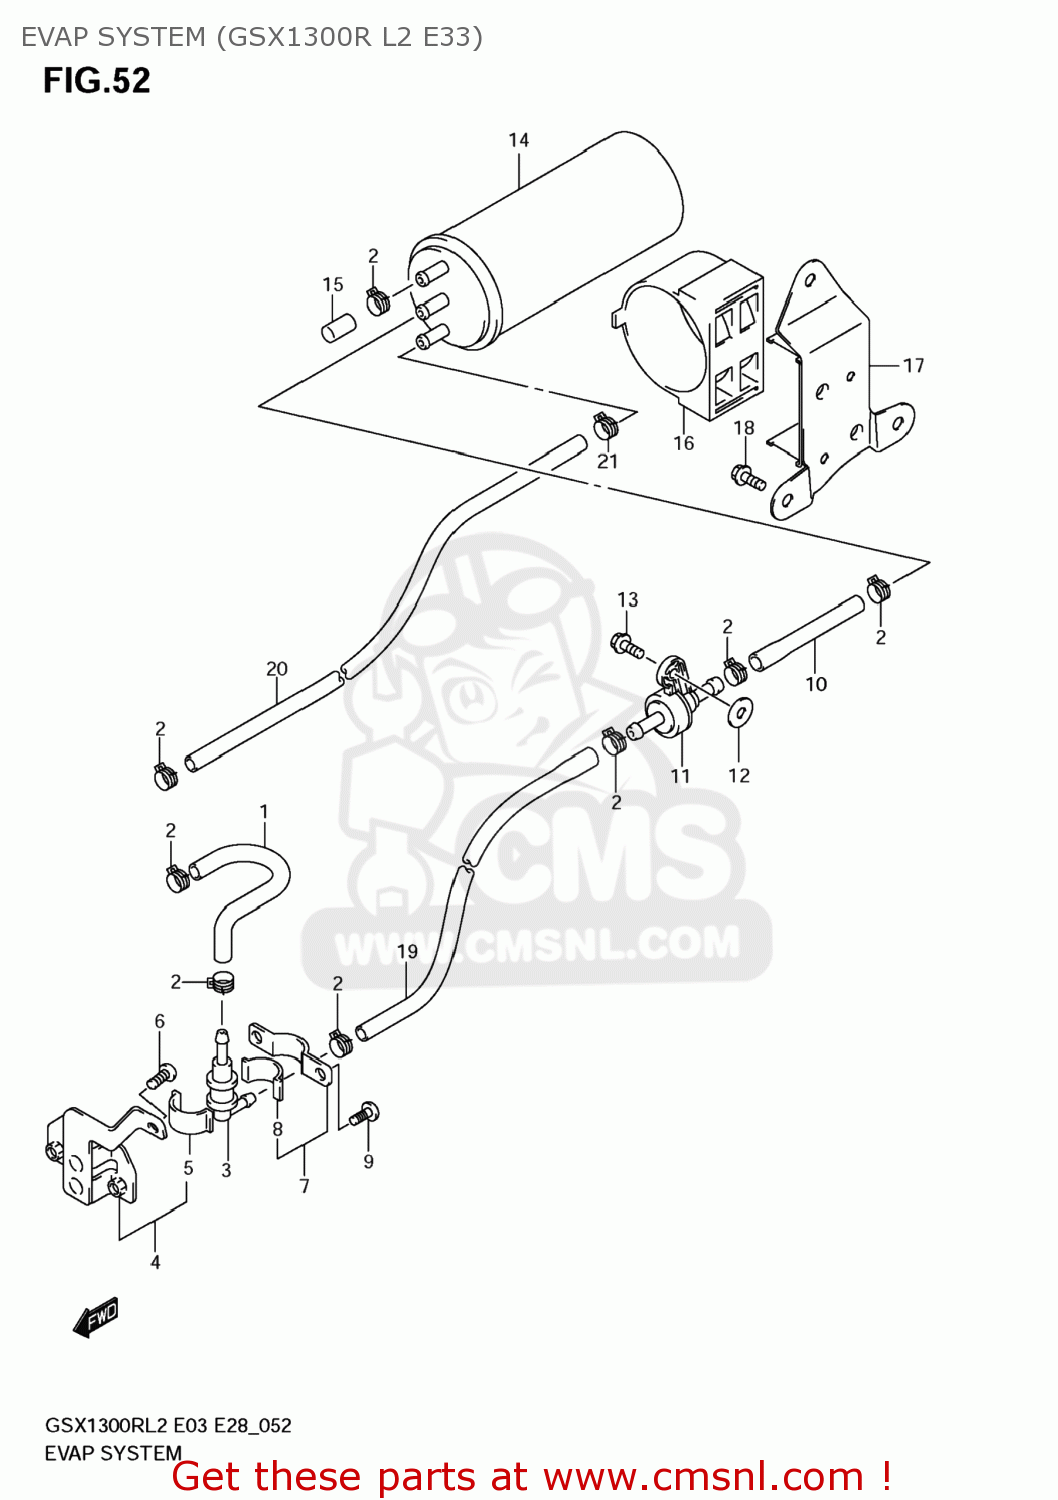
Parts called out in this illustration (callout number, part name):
1	HOSE,TANK & BREATHER VALVE
2	CLIP
3	VALVE,FUEL TANK BREATHER
4	PLATE,TANK BREATHER VALVE
5	CUSHION
6	SCREW
7	PLATE,FUEL TANK BREATHER NO.2
8	CUSHION
9	SCREW
10	HOSE,BRTHR VALVE & 2 WAY
11	VALVE,2 WAY & BREATHER VALVE
12	WASHER(6.5X20X1.2)
13	BOLT
14	CANISTER ASSY,CHARCOAL
15	CAP
16	CUSHION,CANISTER
17	BRACKET,CANISTER
18	BOLT
19	HOSE,2 WAY & CSTR
20	HOSE
21	CLIP
